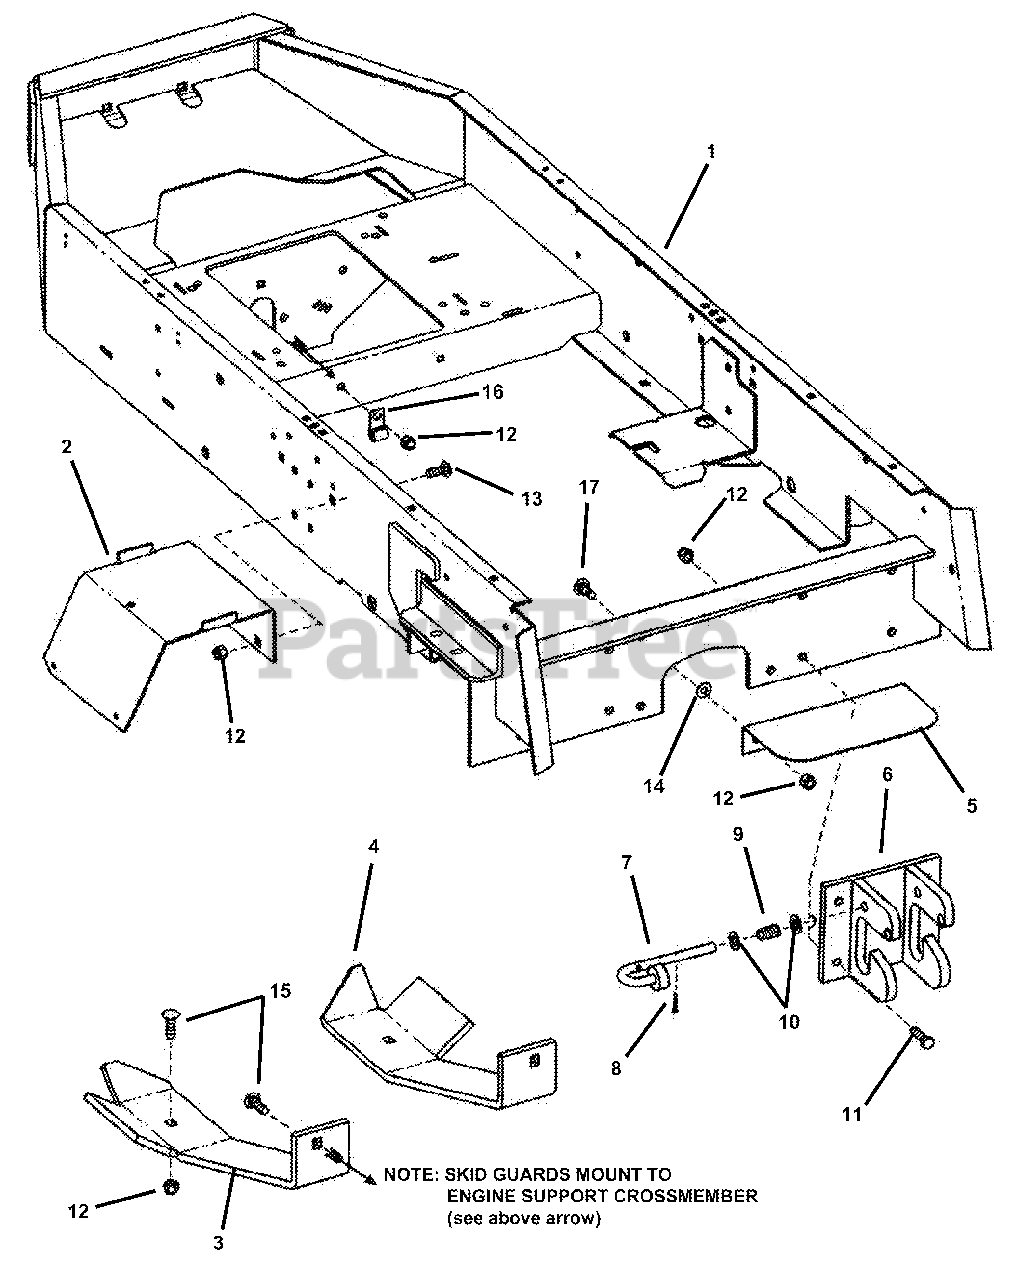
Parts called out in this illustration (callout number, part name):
1	CHASSIS, Lower
2	BRACKET, Battery Support
3	SKID GUARD, R.H.
4	SKID GUARD L.H.
5	SHIELD, Grass
6	PLATE, Hitch
7	PIN, Hitch
8	PIN, Cotter, 1/8 x 3/4"
9	SPRING
10	WASHER, 15/32 I.D. x 15/16" O.D., Flat
11	BOLT, 3/8-16 X 1-1/4" GD5 CZ
12	NUT, 3/8-16 HEX NYLON LOCK
13	BOLT, 3/8-16 x 1" Carriage, Grade 5
14	RETAINER, 3/8" Bolt
15	BOLT, 3/8-16 x 1-1/4", Carriage, Grade 5
16	J-CLIP, Open Cushioned
17	BOLT, 3/8-16 x 1-1/4" Short Neck Carriage, Grade 5
